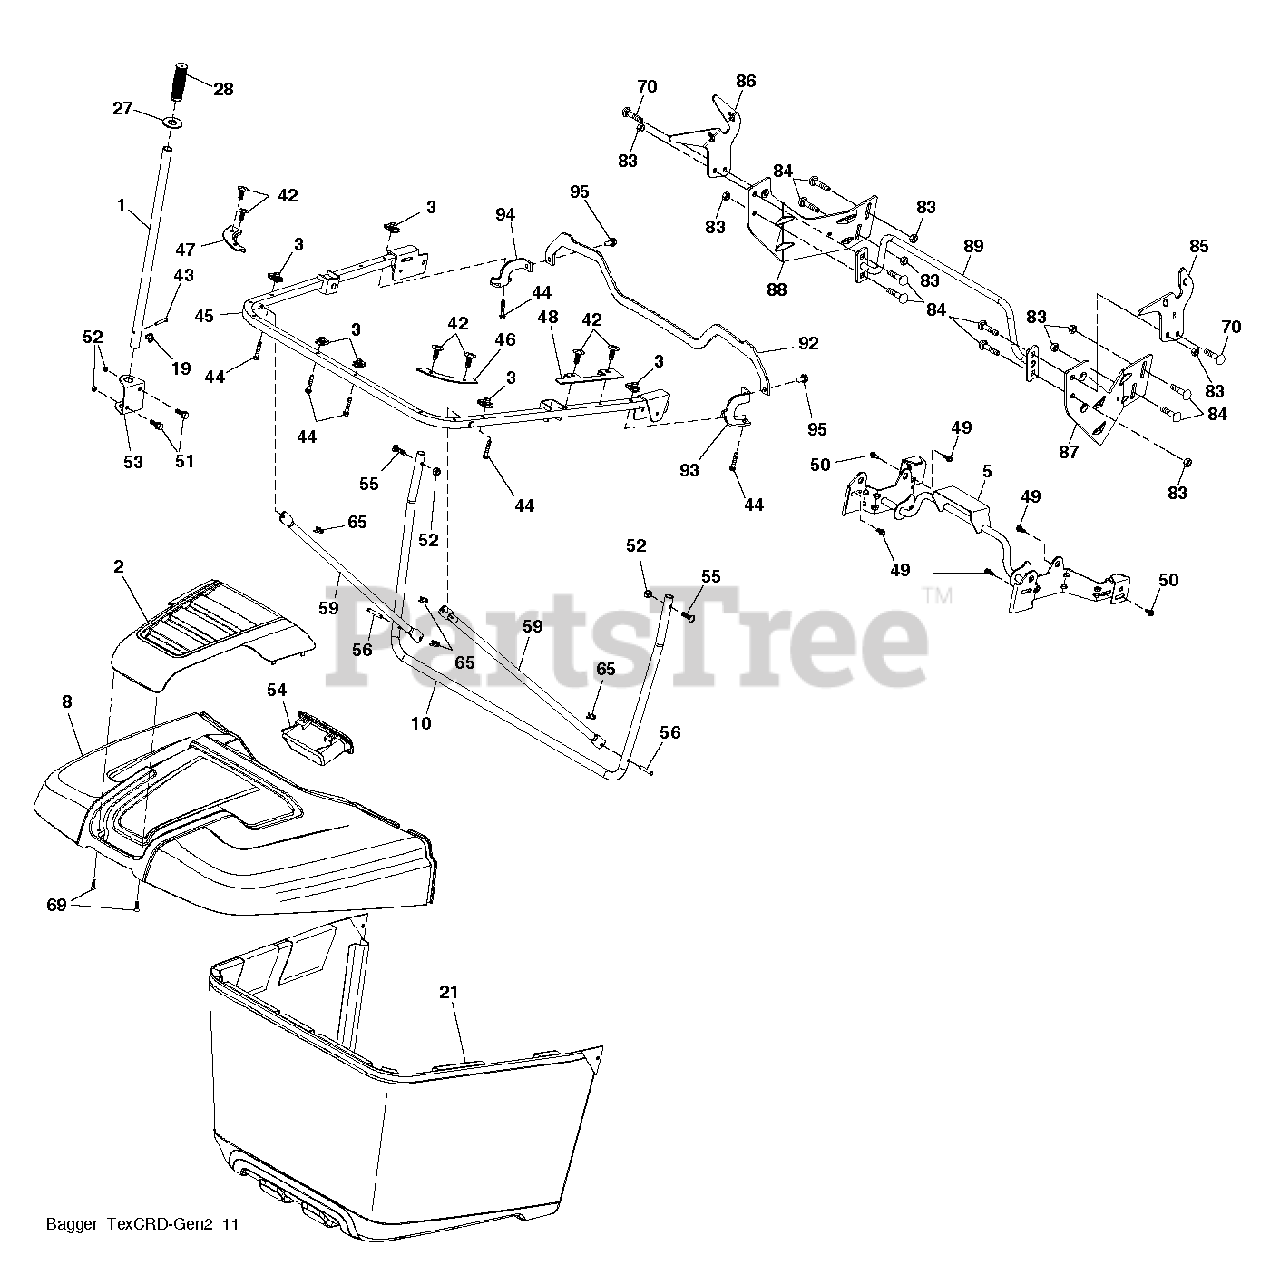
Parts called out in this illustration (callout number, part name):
1	TUBE.HANDLE.BAGGER.CRD/SRD.BLA
2	APPLIQUE.BAGGER
3	1/4-20 U NUT
5	FRAME TEX_CRD_GEN2 UPPER PIVOT
8	BAGGER TOP
10	FRAME TEX_CRD_GEN2 BAGGER FRAM
19	PIN.COTTER.5/16.BOW TI
21	BAGGER.ASM.FABRIC.CRD.GII.HUSQ
27	GROMMET RUBBER GROMMET, DUMP T
28	GRIP.HANDLE.BLACK
42	CLIP CHRISTMAS TREE CLIP
43	RIVET,DRILLED
45	FRAME TEX_CRD_GEN2 UPPER U FRA
46	CONNECTOR RIGHT BAGGER CORNER
47	CONNECTOR LEFT BAGGER CORNER C
48	BAFFLE BAGGER SIDE CLOSE-OUT
49	BOLT, SHOULDER 5/16-18
50	BOLT, 5/16-18 X 1 3/4
51	BOLT.CARR.SQNK.5/16-18UNC.X3/4
52	NUT.71038.31-18.HEX.NYLOCK
53	BRACKET DUMP HANDLE BRACKET, T
54	HANDLE BAGGER TOP FRONT HANDLE
55	BOLT
56	PIN.CLEVIS.183
59	TUBE BAGGER SPREADER TUBE, TEX
65	RETAINER M
69	SCREW,#8.FLAT.HEAD.DRILL.TIP
70	SCREW, 3/8-16X3/4
83	NUT
84	BOLT D
85	BRACKET.RH.PIVOT.MAN.DUMP.BLAC
86	BRACKET.LH.PIVOT.MAN.DUMP.BLAC
87	BRACKET.RH.MID.SUP.BAG.TEX.CRD
88	BRACKET.LH.MID.SUP.BAG.TEX.CRD
89	TUBE.WELD.OFSET.STRUT.BAG.X431
92	BRACKET.PNT.BAGGER.TOP.SUPPORT
93	BRACKET.PNT.RH.SUPPORT.ATTACH
94	BRACKET.PNT.LH.SUPPORT.ATTACH
95	SCREW
